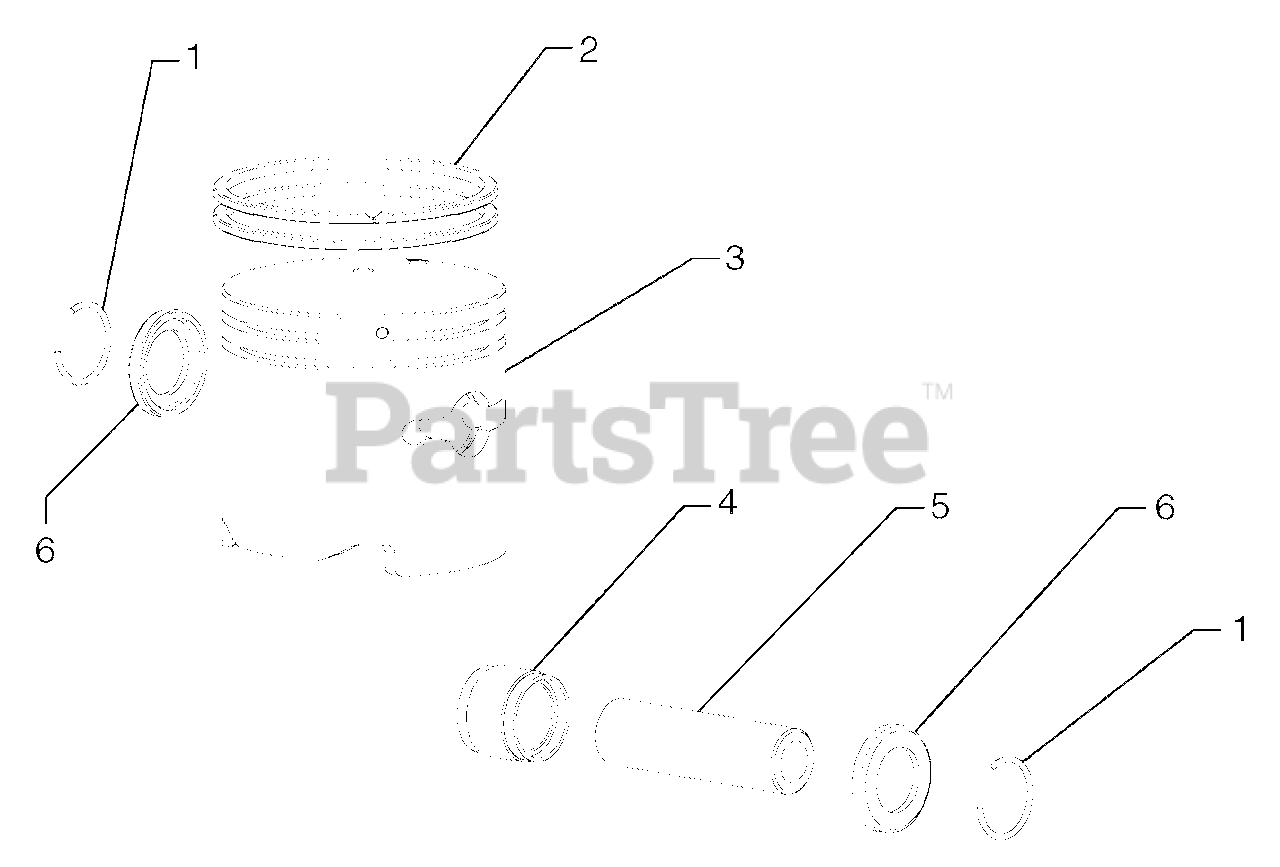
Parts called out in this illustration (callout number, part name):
1	Wrist Pin Clip Ring
2	Piston Ring
4	Needle Bearing (ID8 x 8.8)
5	Wrist Pin
